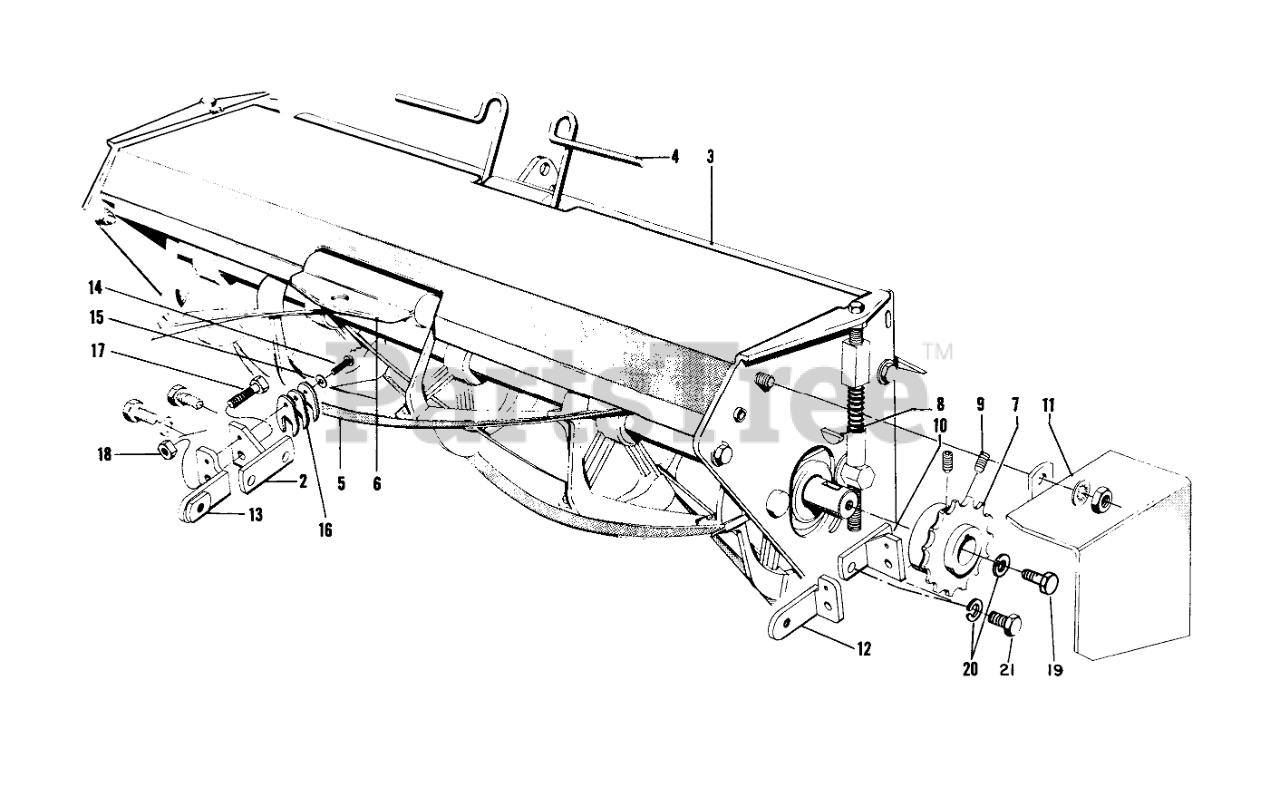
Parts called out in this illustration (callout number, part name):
8	KEY-WOODRUFF
9	SCREW-HSH
14	10-24 X 7/8 RND HD MS
15	WASHER-LOCK, INT
16	FRONT SIDE SHIM
17	SCREW-HH
18	NUT-HEX
19	SCREW-HH
20	WASHER-LOCK, INTERNAL
21	SCREW-HH
